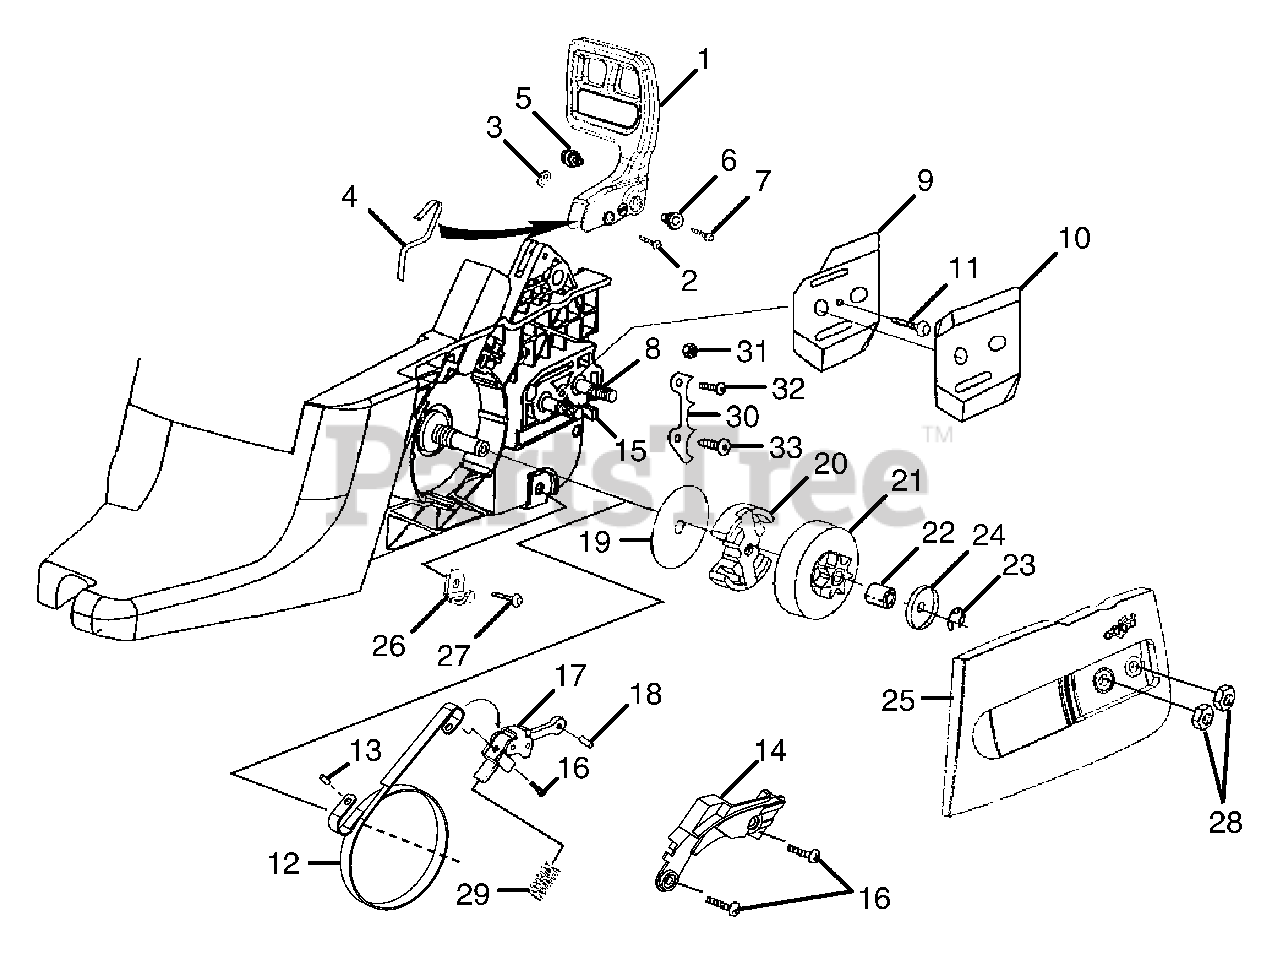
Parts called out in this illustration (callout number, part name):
1	HAND GUARD
2	HAND GUARD ACTUATING PIN
3	RETAINING RING
4	SPRING, HANDGUARD
5	PIVOT, LH
6	PIVOT, RH
7	SCREW (8-32 x 5/8 in.)
8	GUIDE BAR BOLT
9	PLATE, GUIDE BAR
10	PLATE, GUIDE BAR
11	SCREW (6-19 x 1/2 in.)
12	BRAKE BAND
13	PIN, ROLL
14	BRAKE BAND COVER
15	ADJUSTING PIN KIT
16	SCREW (8-16 x .320)
17	CHAIN BRAKE LINK
18	PIN, ROLL
19	THRUST WASHER
20	CLUTCH & HARDWARE
21	SPROKET DRUM (.325 PITCH)
22	BEARING, NEEDLE
23	RING, RETAINING
24	WASHER
25	DRIVE CASE COVER
26	CHAIN CATCHER
27	SCREW (10-24 x 1/2 in.)
28	NUT, HEX
29	SPRING, COMPRESSION
30	BUMPER SPIKE
31	LOCK NUT, HEX (10-24)
33	SCREW, TRUSS HD.
